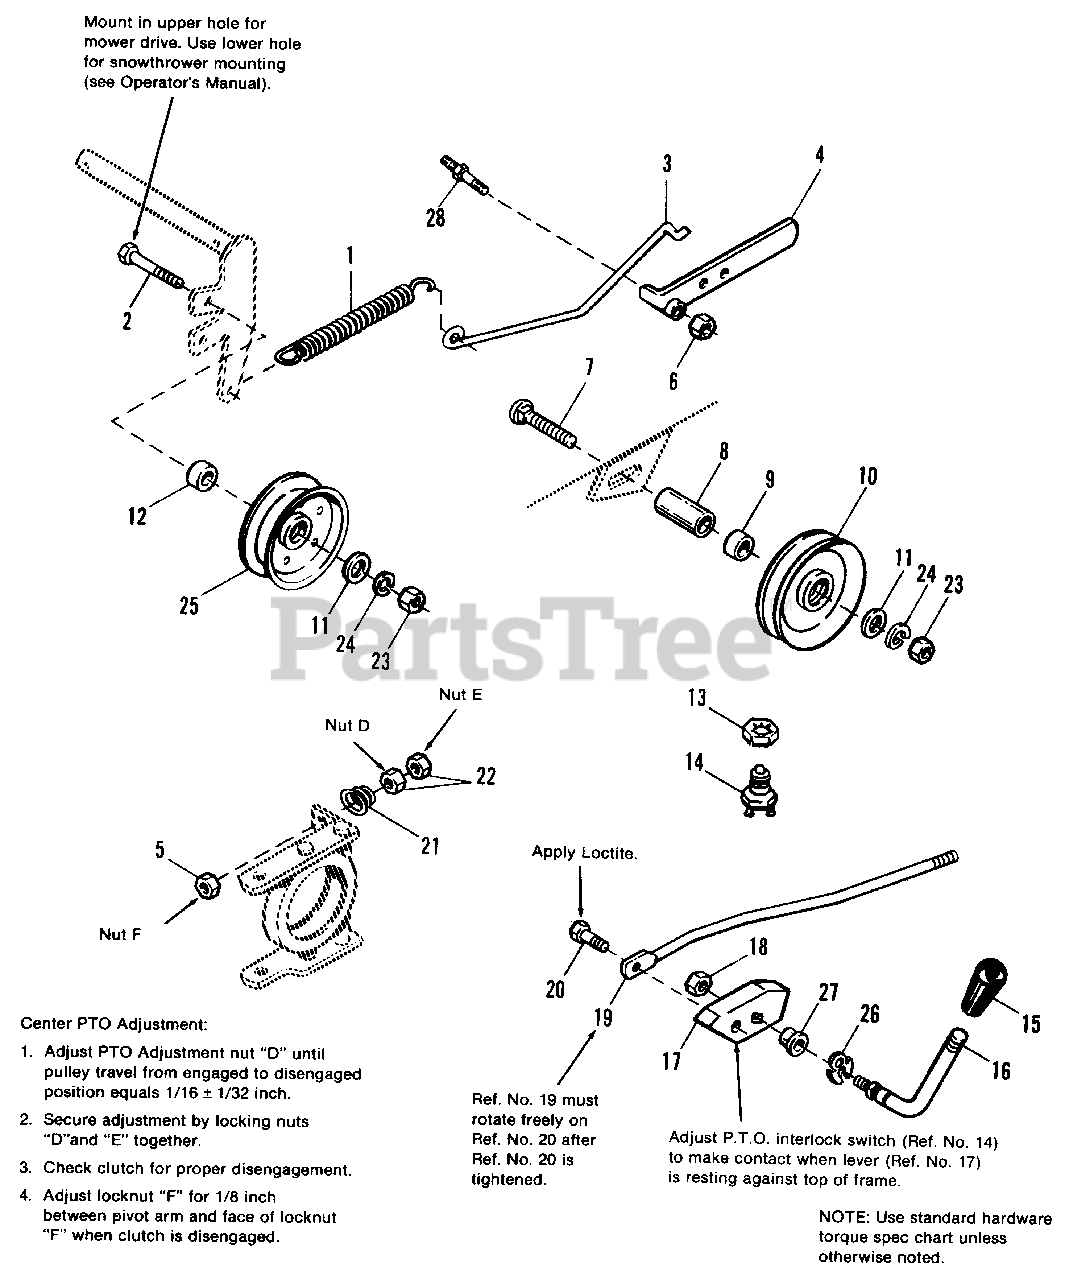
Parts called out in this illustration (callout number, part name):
1	SPRING, Tension
2	CAPSCREW, Hex Hd., 3/8-16 x 2
3	ROD, Tension
4	HANDLE ASSY.
5	LOCKNUT, Hex, 5/16-18
6	LOCKNUT, Hex, 7/16-14
7	BOLT, Carriage, 3/8-16 x 1-3/4
10	PULLEY ASSY., w/ Bearings
11	WASHER, Plain, 3/8
14	SWITCH, Interlock
15	KNOB, Soft
16	HANDLE, PTO, Clutch
18	LOCKNUT, Hex, 3/8-16
19	ROD ASSY., Control
22	NUT, Hex, Full, 5/16-18
23	NUT, Hex, Full, 3/8-16
24	LOCKWASHER, 3/8
25	PULLEY, Idler
26	KLIPRING,1/2
27	BUSHING
